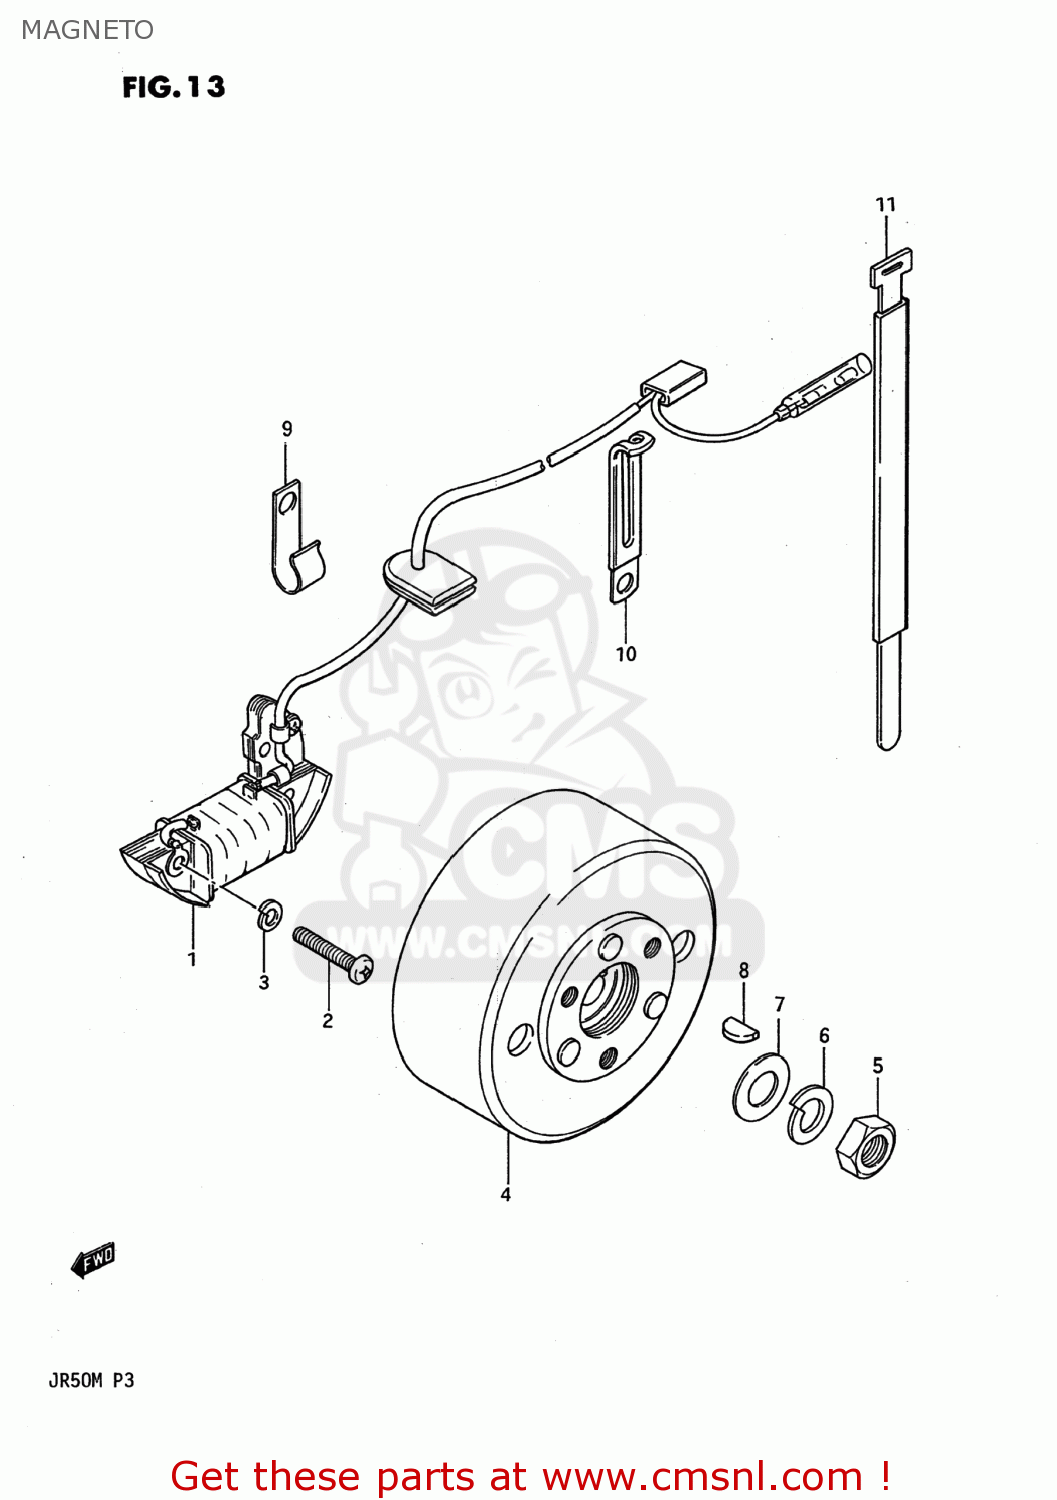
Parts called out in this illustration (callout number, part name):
1	STATOR ASSEMBLY
2	SCREW 4X25
3	WASHER,LOCK 4M
4	ROTOR ASSY
5	NUT
6	WASHER,LOCK,10
7	WASHER
8	KEY
9	CLAMP
10	CLAMP L:35
11	CLAMP
